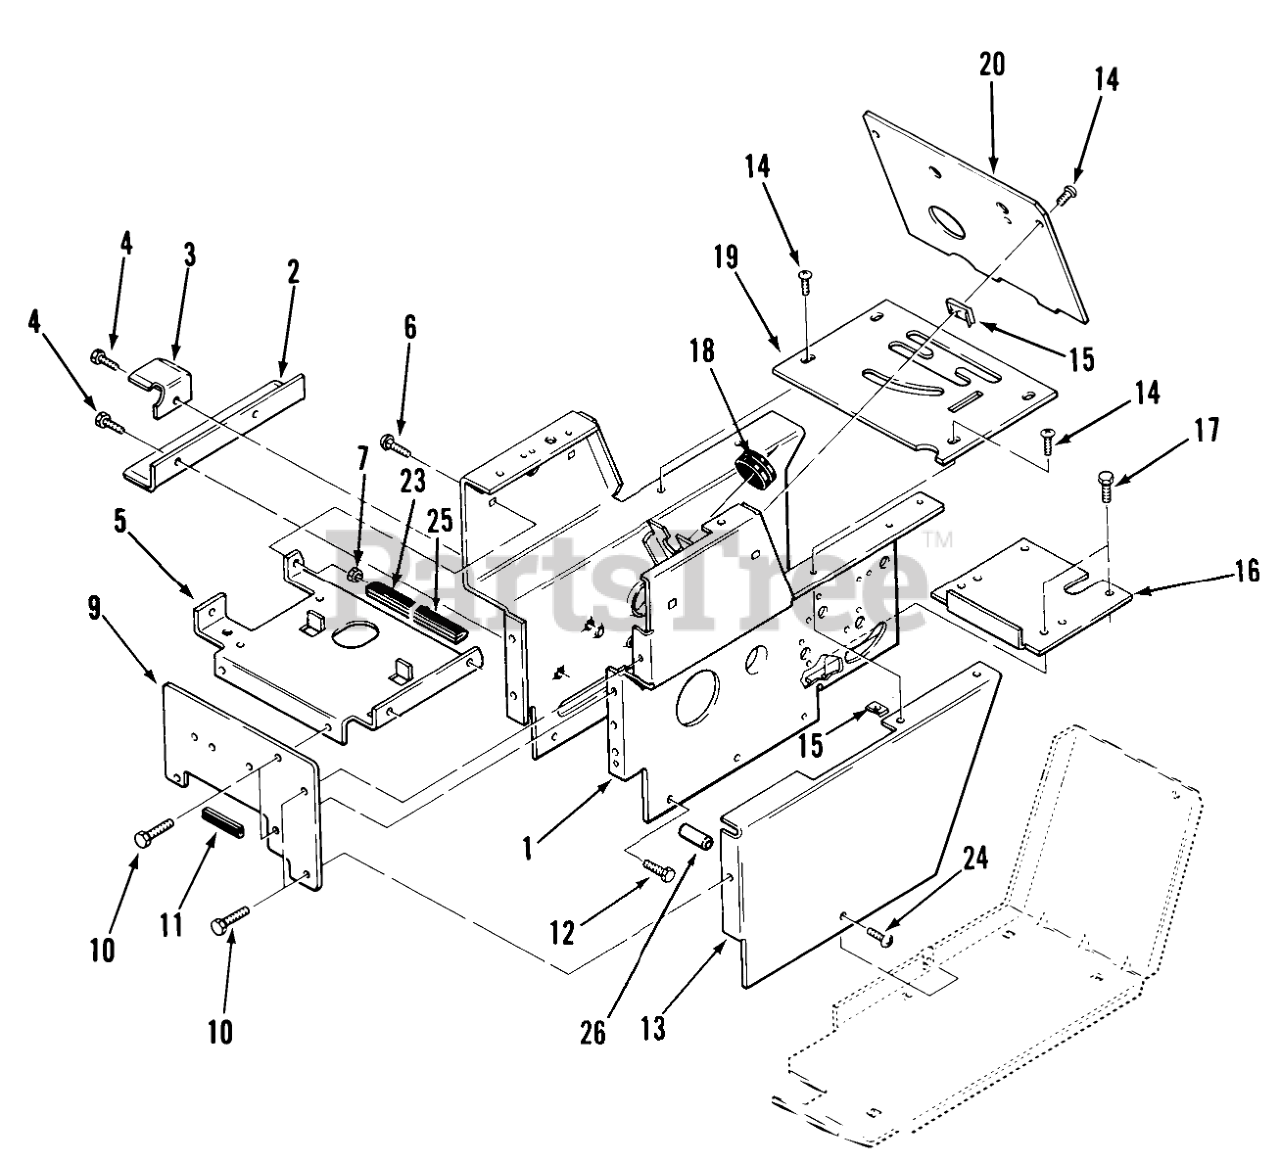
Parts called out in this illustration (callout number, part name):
1	Hoodstand
2	ANGL-BLT GURDB
3	BRCKET-BLT SUTB
3	Belt Bracket
4	SCREW
5	SUPPORT-BATTERY B
6	CARRIAGE BOLT -4
7	Nut
9	Front Plate
10	SCREW
11	EDGE TRIM 2" 102896
12	SCREW
13	Side Cover LH
14	SCREW-PPH
16	Cover-Dust
17	SCREW
18	GROMMET
19	PLATE SHIFT B
19	PLATE SHIFT PATTE B
20	PLATE HOODSTAND B
23	EDGE TRIM 5" OF 102896
24	Screw
25	EDGE TRIM 2" 102896
26	Spacer 417-8 Only
